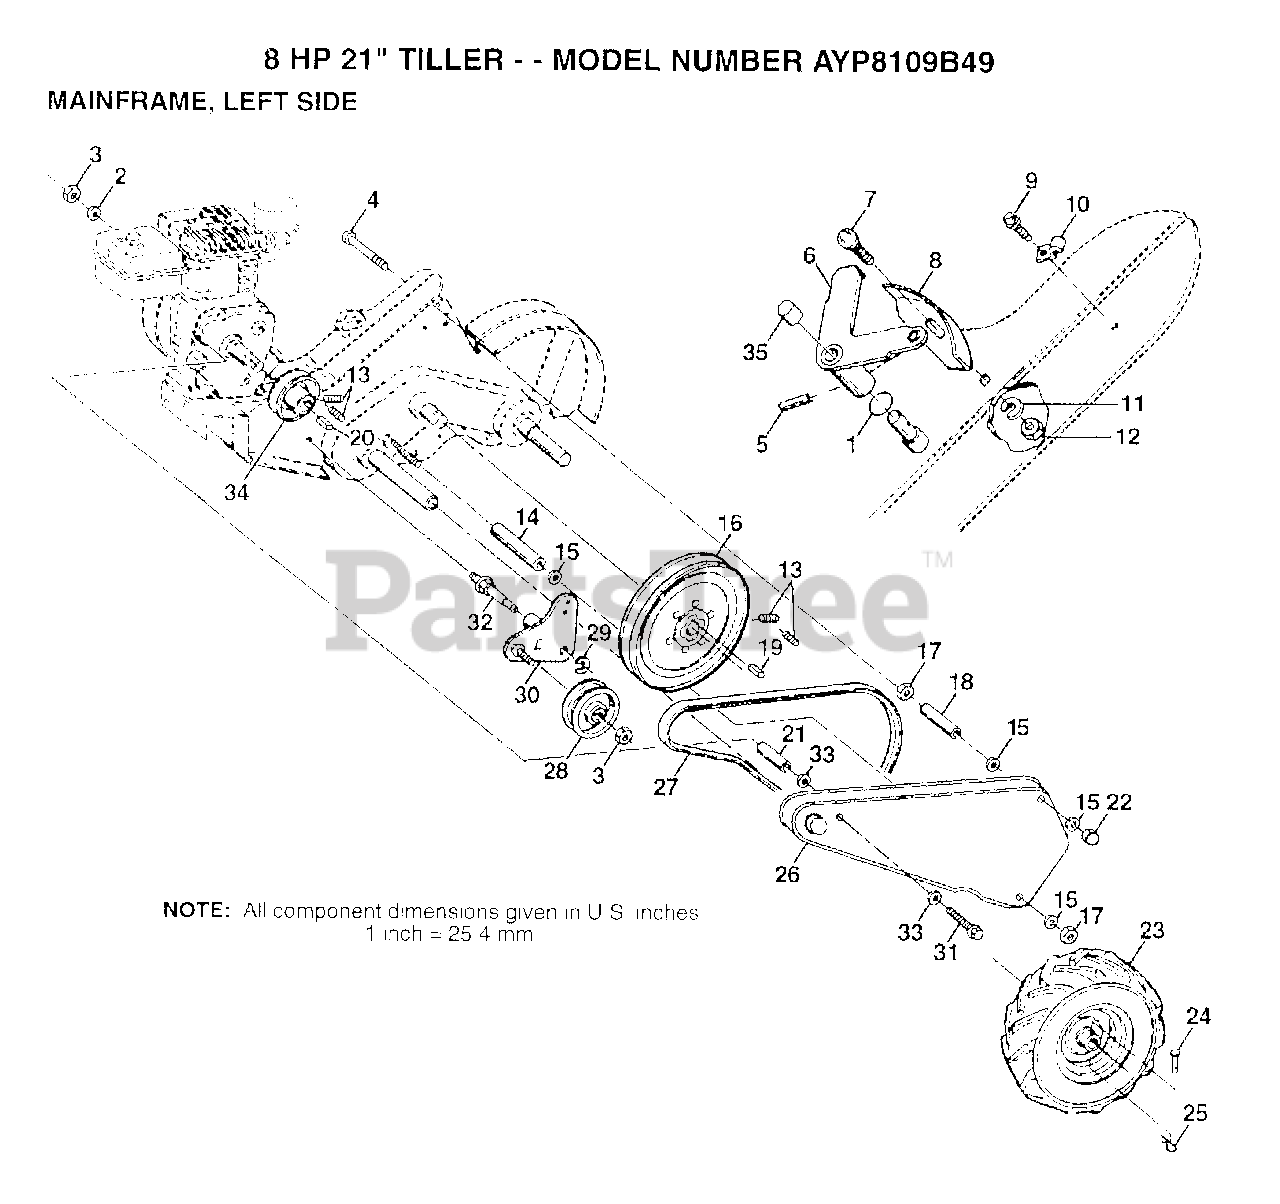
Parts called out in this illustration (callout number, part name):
1	O-RING TI
2	LOCKWASHER
3	NUT.HEX.3/8-16UNC
4	BOLT TI
6	LEVER ASM CRT
7	BOLT
8	PANEL TI
10	CONDIUT CLIP T
11	LOCKWASHER
13	SET SCREW
14	SPACER TI
15	WASHER
16	"SHEAVE 10"" CRT"
17	NUT.HEX.5/16-18
18	SPACER TI
19	KEY T
20	KEY TI
21	SPACER.SPLIT
22	NUT TI
23	TIRE TI
24	RIVET.PAN HD.1.75
25	SPRING.RETAINER
26	GUARD BELT RED
27	BELT.DRIVE
29	KLIP RING
31	BOLT1/2-20UNF2.75
32	SHAFT.IDLER
34	SHEAVE CRT
35	CAP PLUNGER BLACK
